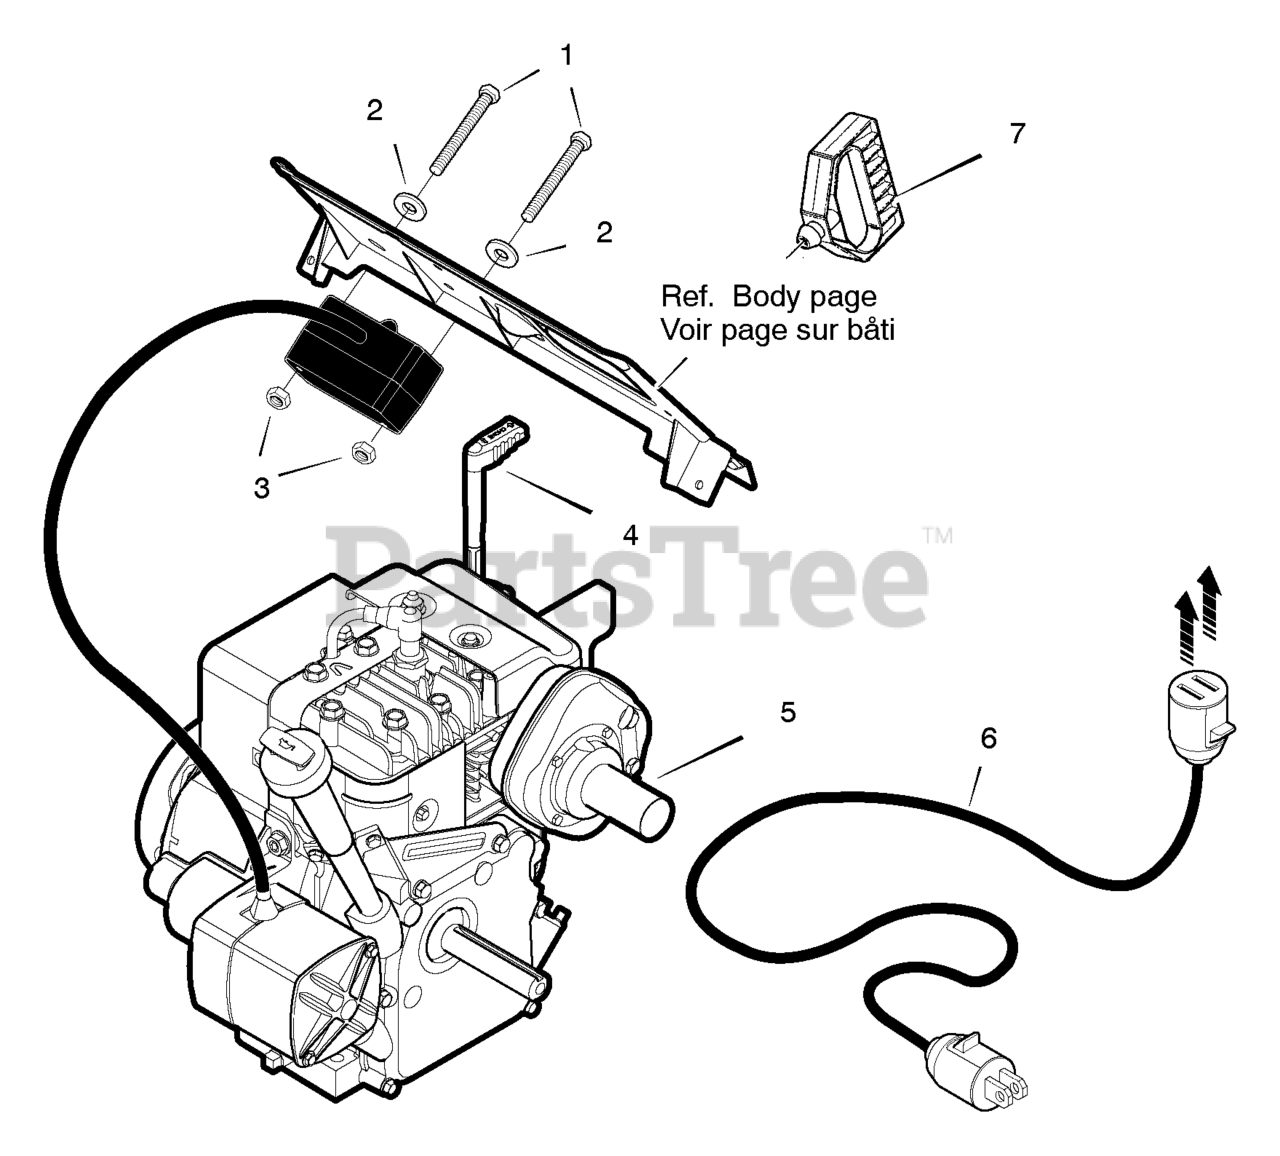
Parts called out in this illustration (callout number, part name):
1	Screw, No. 8-32 x 3.00
2	Washer
3	Nut, Keps No. 8
4	Lever, Choke
5-1	Muffler
5-2	Gasket, Muffler
5-3	Bolt, Muffler
5-4	Washer, Split Lock
5-5	Nut, Hex 5/16-18
5-6	Bolt, Hex 5/16-18
6	CORD, Electric, 10FT. 110V
7	Grip, Mitten
